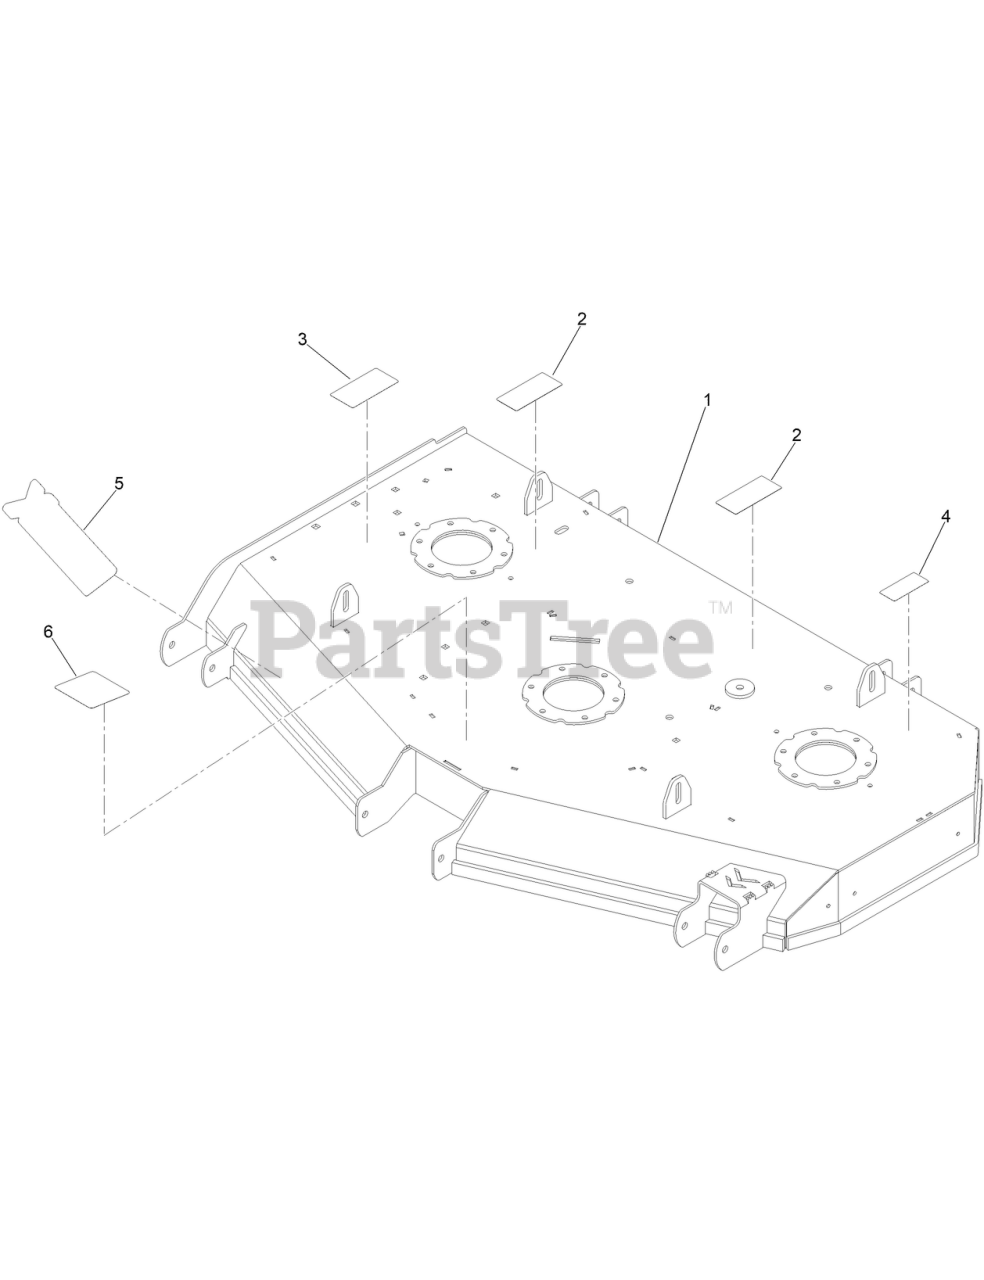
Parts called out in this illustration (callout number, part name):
2	DECAL-ROTATING FAN HAZARD
3	DECAL-DANGER, DECK
4	DECAL-SAFETY BLADE TORQUE
5	DECAL-XTF
6	DECAL-DECK BELT ROUTING
